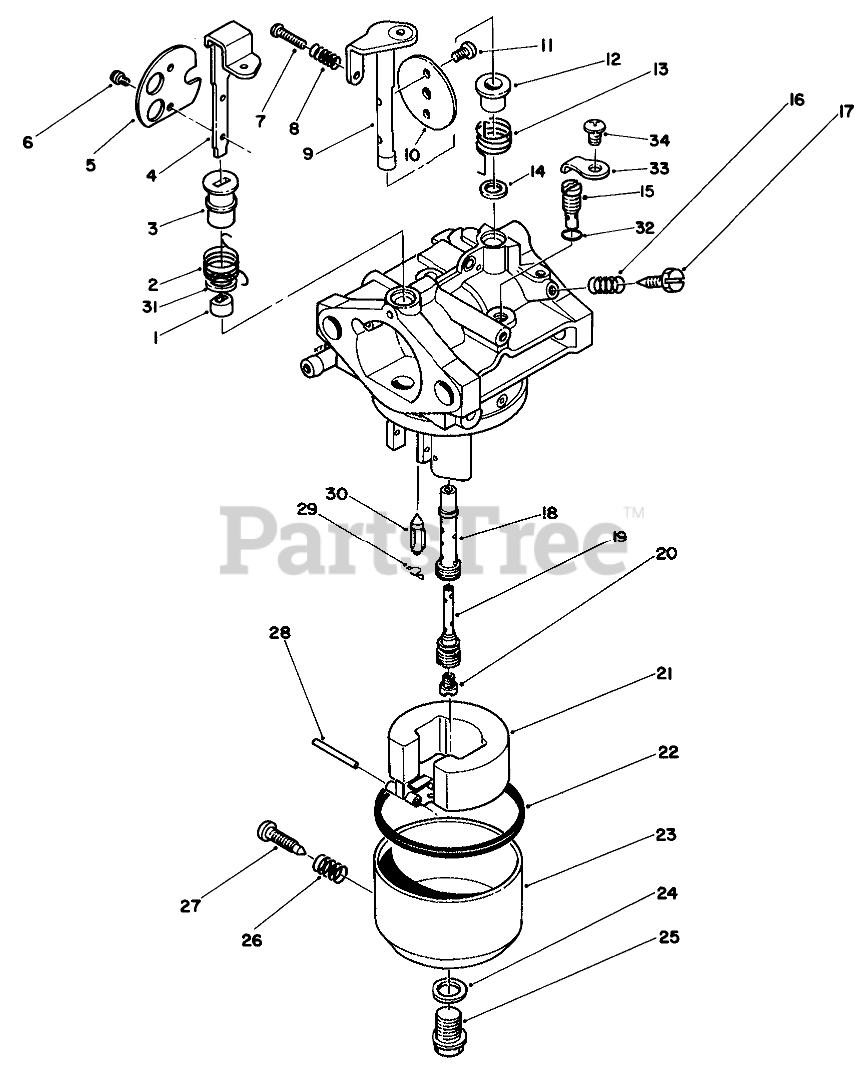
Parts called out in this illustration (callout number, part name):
1	Ring
4	Shaft-Choke
5	Valve-Choke
9	Shaft-Throttle
10	Valve-Throttle
14	Seal
19	Pipe-Bleed
22	Gasket
23	Chamber-Float
27	Screw
28	Pin
29	Clip
30	Valve-Needle
